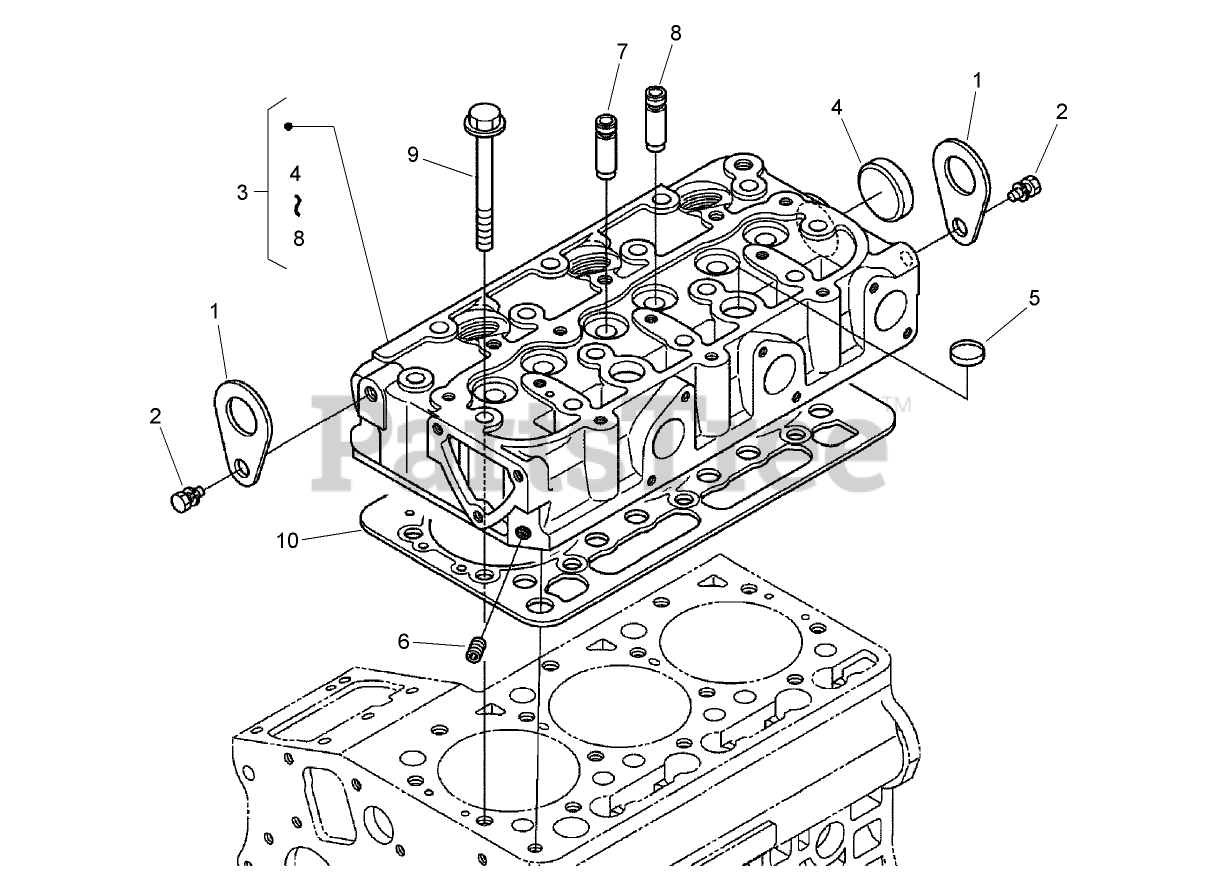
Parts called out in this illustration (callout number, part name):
1	HOOK-ENGINE
3	HEAD-CYLINDER
4	CAP-SEALING
5	CAP-SEALING
6	PLUG
7	GUIDE-VALVE, INLET
8	GUIDE-VALVE, EXHAUST
9	BOLT-HEAD, CYLINDER
10	GASKET-HEAD, CYLINDER
